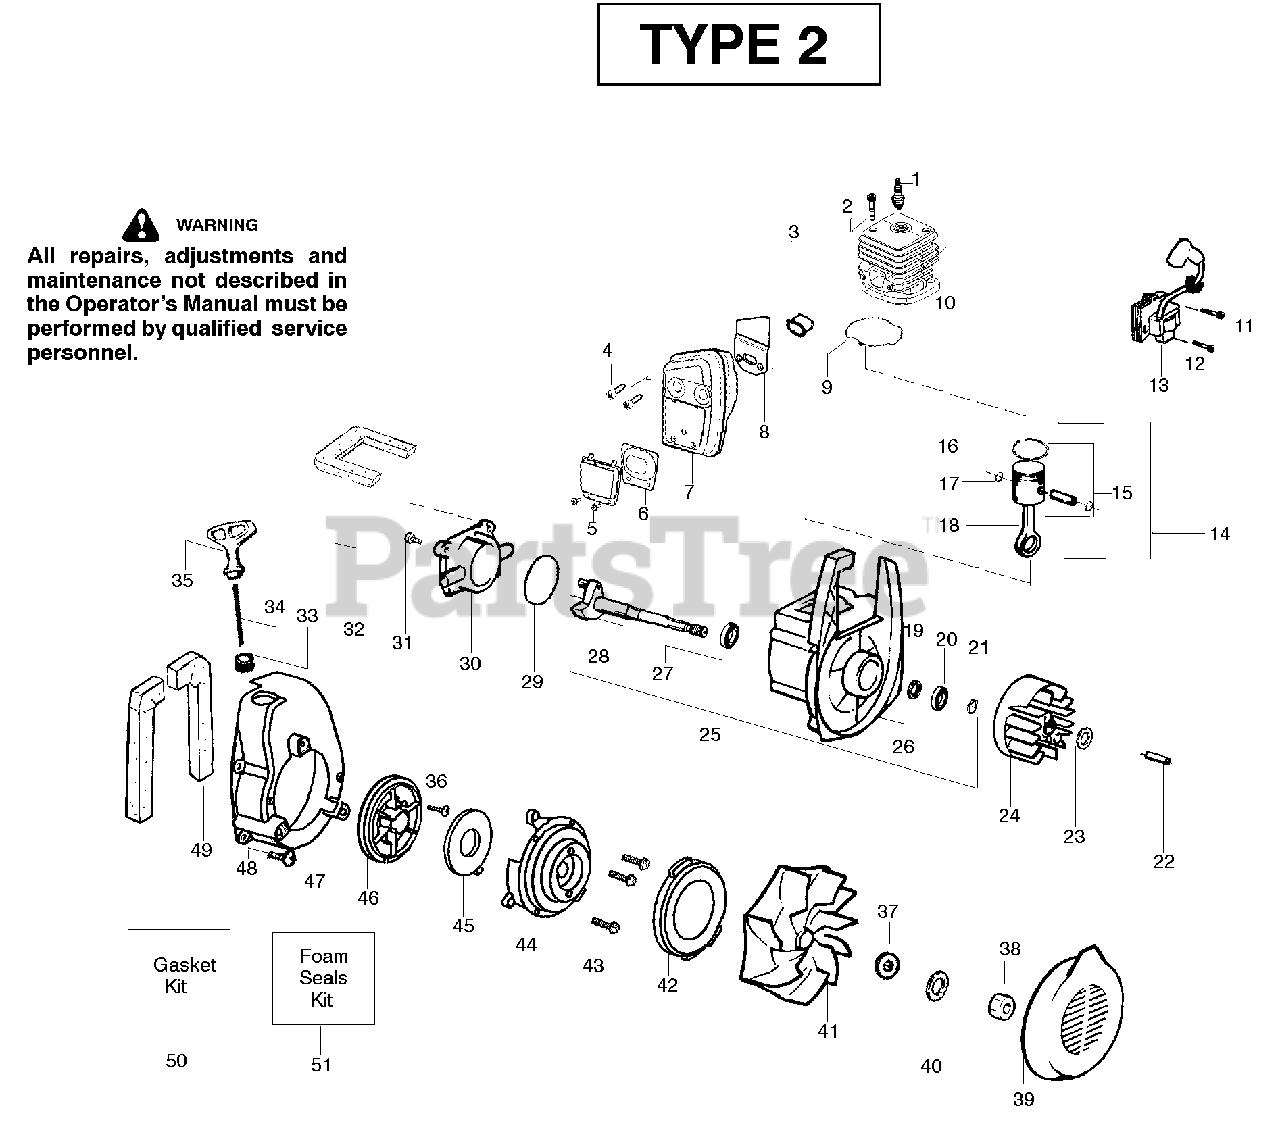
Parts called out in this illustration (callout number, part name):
1	Spark Plug (RCJ-6Y)
3	Insulator-Heat
4	Screw-Muffler-Internal
6	Kit-Spark Screen
7	Kit-Muffler
8	Gasket-Baffle (kit)
9	Gasket-Cylinder (kit)
11	Grommet-Ign. Module
12	Screw-Ignition Module
13	Ignition Module
14	Kit-Piston/Rod
15	Kit-Piston
16	Piston Ring
17	Retainer-Piston Pin
18	Assy-Connecting Rod
20	Bearing-Outer
21	Retainer Ring-C'chaft
22	Spacer-Flywheel
24	Assy-Flywheel
25	Assy—Crankcase/Crank shaft
26	Assy-Crankcase
27	Bearing-Inner
28	Assy-Crankshaft
29	O-ring-C/case (kit)
30	Cover-Crankcase
31	Screw
32	Foam-219mm (kit)
33	Eyelet-Flange
34	Kit-Rope
35	Handle-Starter
37	Washer-Belleville
41	Kit-Impeller Assy.
44	Housing-Pulley
45	Spring-Starter
46	Kit-Starter Pulley
48	Screw
49	Foam-182mm (kit)
50	Kit-Gasket
51	Kit-Foam Seals
